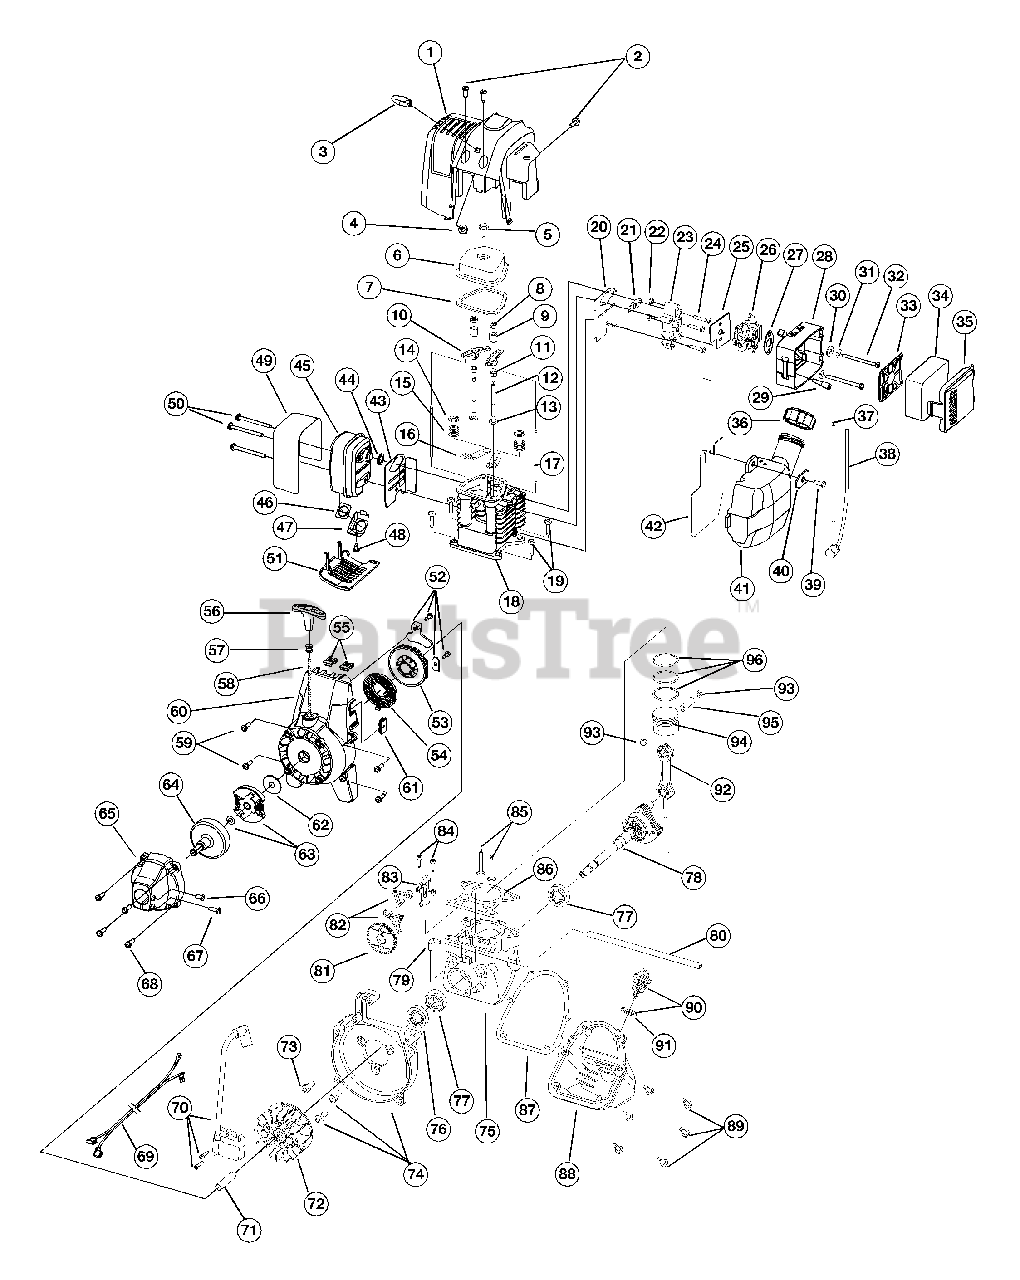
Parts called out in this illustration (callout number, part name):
1	Engine Cover
2	Engine Cover Screws
3	Starter Rope Eyelet
4	Eyelet Nut
5	Valve Cover Screw
6	Valve Cover
7	Valve Cover Gasket
8	Rocker Adjustment Nut
9	Rocker Arm Pivot
10	Rocker Arm
11	Hex Nut
12	Rocker Arm Stud
13	Washer
14	Valve Spring Retainer
15	Valve Spring
16	Push Rod Guide
17	Push Rod
18	Cylinder Head
19	Cylinder Screw
20	Intake Baffle
21	Carburetor Mount Gasket
23	Carburetor Mount
24	Carburetor Mount Screw
25	Carburetor Gasket
26	Carburetor with Primer
27	Air Filter Gasket
28	Air Filter Cover Assembly
29	Breather Tube Assembly
30	Grommet Washer
31	Washer
32	Air Filter Mounting Screw
33	Air Filter Plate
34	Air Filter
35	Air Filter Cover
36	Fuel Cap
37	Fuel Return Line
38	Fuel Pick-Up Line with Filter
39	Screw
40	Washer
41	Fuel Tank Assembly
42	Fuel Tank Shield
43	Muffler Baffle
44	Muffler Gasket
45	Muffler
46	Spark Arrestor Screen
47	Screen Cover
48	Screw
49	Muffler Shield
50	Muffler Mounting Screw
51	Muffler Cover
52	Pulley Retainer Assembly
53	Recoil Pulley
54	Recoil Spring
55	Nut Clip
56	Pull Handle
57	Rope Guide
58	Rope
59	Starter Housing Screw
60	Starter Housing Assembly
61	Wire Grommet
62	Clutch Washer
63	Clutch with Washer
64	Clutch Drum
65	Clutch Cover
66	Anti-Rotation Screw
67	Screw
68	Clutch Cover Screw
69	Switch Wire Assembly
70	Ignition Module with Screws
71	Spacer
72	Flywheel
73	Screw
74	Shroud Assembly with Screws
75	Crankcase Assembly
76	Oil Seal
77	Bearing
78	Crankshaft
79	90° Elbow
80	Breather Hose
81	Cam Gear
82	Cam Follower
83	Cam Bracket
84	Cam Bracket Screw
85	Valves, Intake and Exhaust
86	Cylinder Gasket
87	Oil Pan Gasket
88	Oil Pan
89	Oil Pan Screw
90	Dipstick Assembly
91	O-Ring
92	Connecting Rod
93	Wrist Pin Button
94	Piston
95	Wrist Pin
96	Piston Ring Set
